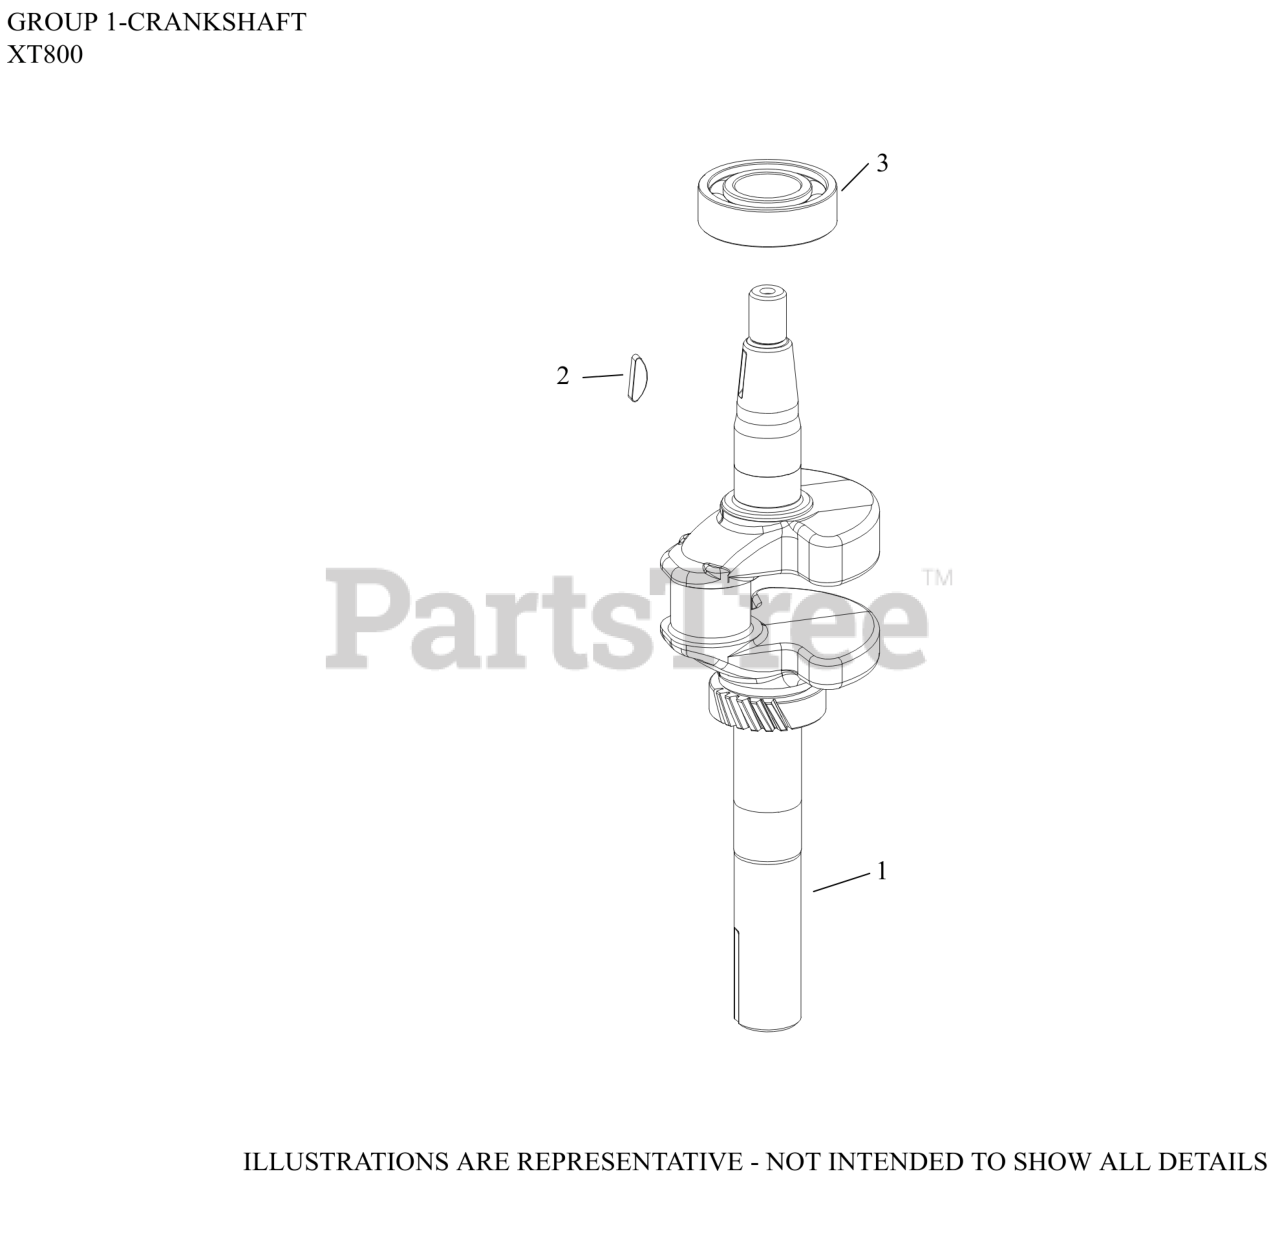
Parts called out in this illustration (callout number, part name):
1	CRANKSHAFT ASSEMBLY-USE 14 014 153-S
2	KEY, FLYWHEEL
3	BEARING, BALL
